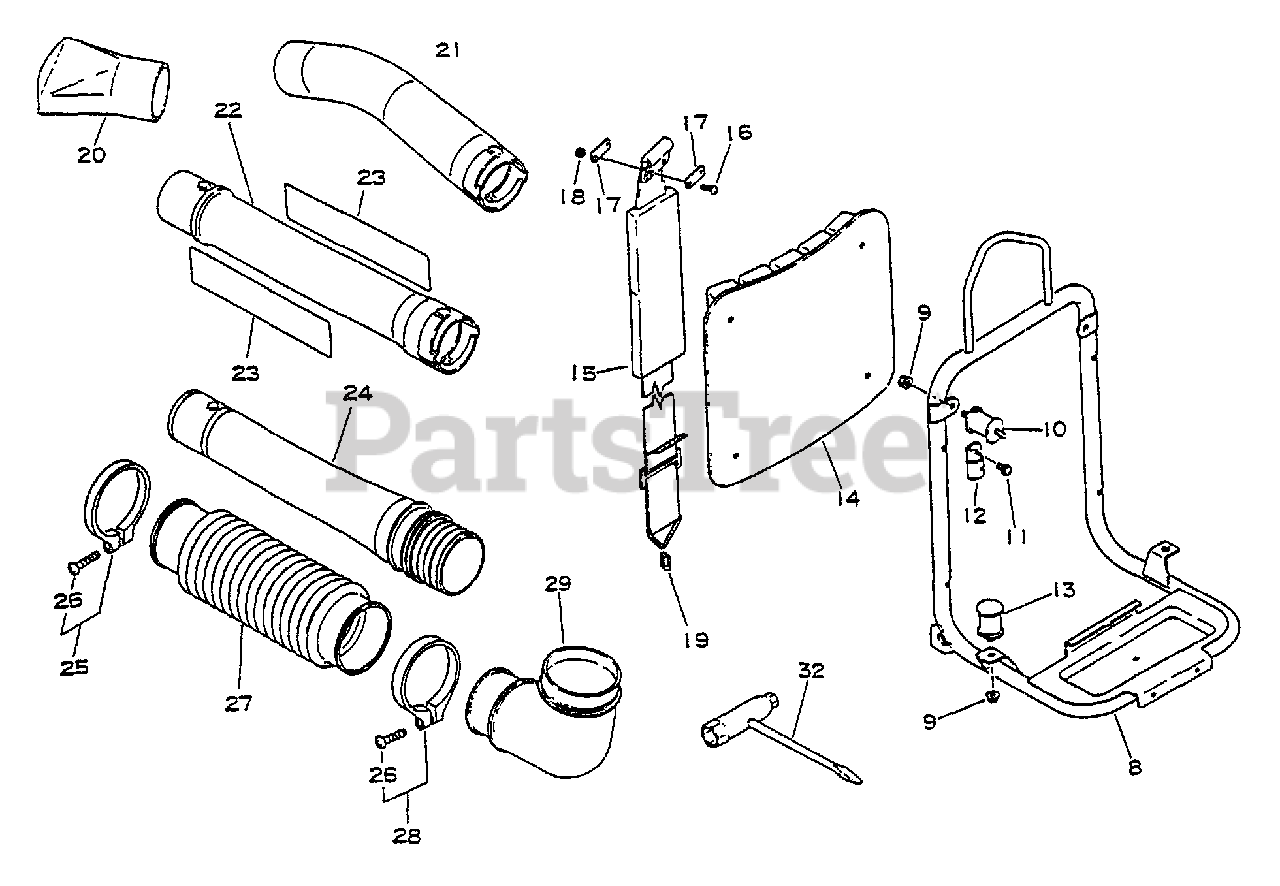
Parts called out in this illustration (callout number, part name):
8	FRAME, BACKPACK
9	NUT, FLANGE M6
11	SCREW 5×10
12	BRACKET, CUSHION
14	CUSHION, BACKPACK
15	HARNESS ASSY, BACKPACK
16	SCREW 5×14
18	NUT, LOCK M5
19	RING, STRAP
20	NOZZLE - FAN HEAD
21	TUBE, BLOWER - CURVED
22	BLOWER TUBE KIT - STRAIGHT
23	LABEL - ECHO
24	TUBE, BLOWER - SWIVEL
25	CLAMP KIT
26	SCREW 5×25
27	TUBE, FLEXIBLE
28	CLAMP KIT
32	T-WRENCH 10×19 MM
